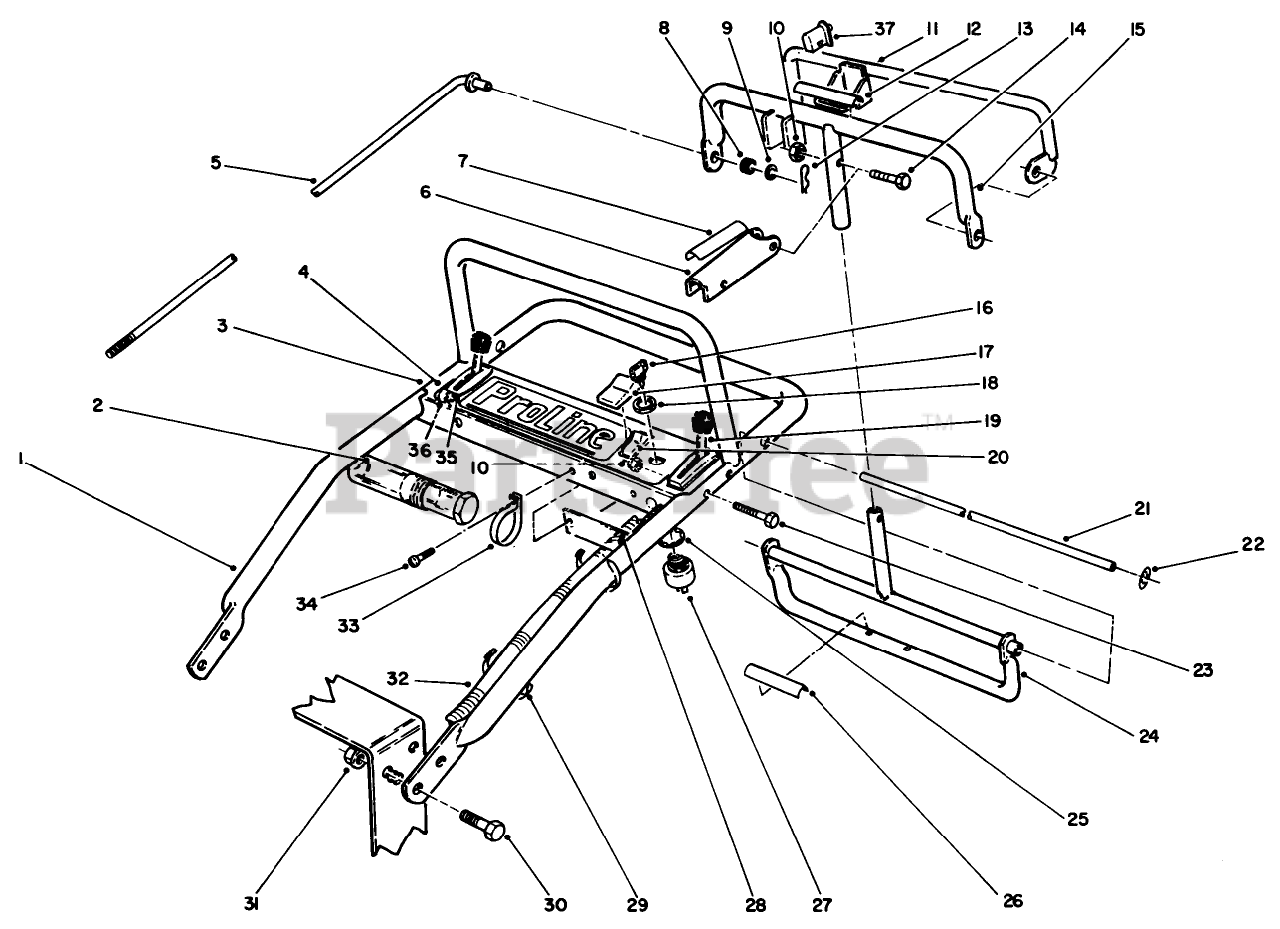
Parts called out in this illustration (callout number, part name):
2	TUBE-MANUAL
4	DECAL-CNTRL PANEL-30175
5	ROD-CONTROL
7	DECAL-LEVER, PARKING
8	GROMMET-RUBBER
9	WASHER-FLAT
10	NUT-LOCK, NI
11	SWITCH-BAIL
12	DECAL
14	SCREW-SHH
16	KEY-IGNITION
17	BOOT-SWITCH
18	NUT-HH
21	PIVOT ROD
22	NUT-PUSH-ON, CIRCULAR
23	SCREW-SHH
25	WASHER-LOCK
26	DECAL
27	SWITCH-STARTER
29	TIE-CABLE
30	SCREW-HHF
31	NUT-HF
33	CLAMP-R
34	SCREW-HWHTF
35	CHOKE CONTROL
36	SPACER
